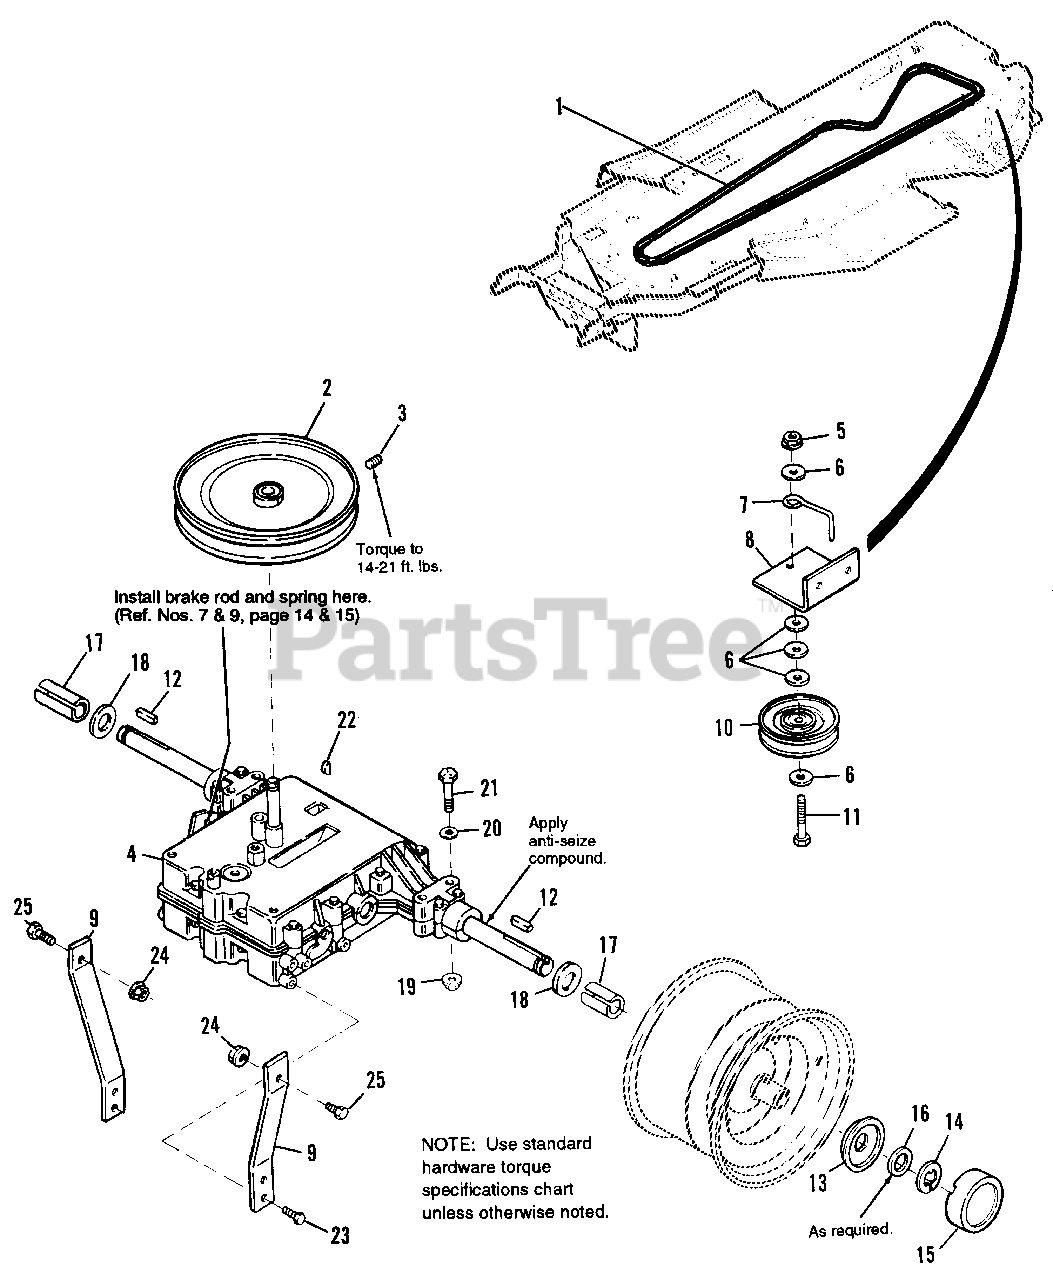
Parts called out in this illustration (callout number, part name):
2	PULLEY ASSY., Driven
3	SETSCREW, 5/16-18 x 1/2
5	NUT, Flange Whizlock, 3/8-16
6	WASHER, Plain, 3/8
7	BELT STOP
8	BRACKET, Pulley
9	SUPPORT, Transmission
10	PULLEY, "V"
11	CAPSCREW, Hex, 3/8-16 x 1-3/4
12	KEY, 3/16 Sq. x 1-1/2
13	RETAINER, Hubcap
16	WASHER, Rear Axle (Use as required)
17	SPACER, Rear Axle
19	NUT, Flange Lock, 5/16-18
20	WASHER, Plain, 5/16
21	CAPSCREW, Hex Hd., 5/16-18 x 2-1/2
22	KEY
23	SCREW, Taptite, 5/16-18 x 5/8
24	NUT, Hex, Flange, 5/16-18
25	SCREW, Whiz, 5/16-18 x 3/4
26	SCREW, Taptite, 5/16-18 x 5/8
